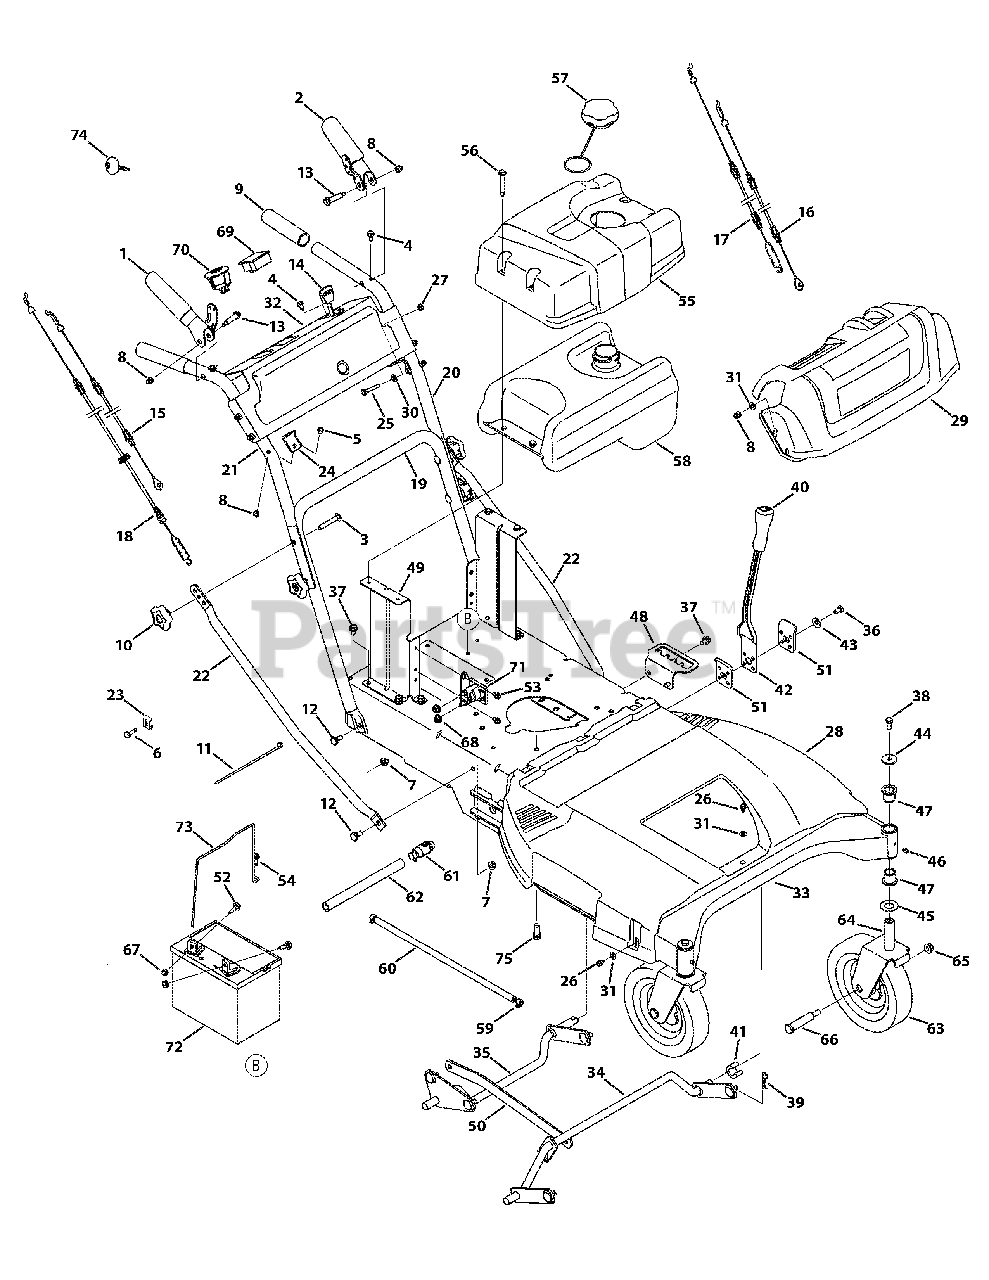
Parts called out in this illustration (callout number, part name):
1	Right Hand Lever Assembly Bracket
2	Left Hand Lever Assembly Bracket
3	Screw, Carriage, 5/16-18 x 2.25
4	Screw, 1/4-20 x 0.500
5	Hex Screw, 1/4-20 x 1.50
6	Screw, #10-32 x 0.625
7	Nut, Flangelock, 5/16-18
8	Lock Nut Cap, 1/4-20
9	Grip, 1.0 ID x 5.0 LG
10	Star Knob, 5/16-18
11	Cable Tie, 3/16 x .05 x 7.4
12	Screw, Shoulder, .435 x .178-5/16 x .56
13	Screw, Shoulder, .375 x 1.355 x 1/4-20
14	Throttle/Choke Cable, 38.0 x 1.1 EXT
15	RH Brake Cable
16	LH Brake Cable
17	Wheel Clutch Cable
18	Deck Clutch Cable
20	Upper LH Handle
21	Upper RH Handle
22	Adjustable Handle Brace
23	Casing Clamp
24	RH Cable Mount Bracket
24	LH Cable Mount Bracket
25	Hex Screw, 1/4-20 x 1.75
26	Screw, 1/4-14 x 0.625
27	Nut, Hex, 1/4-20
28	Belt Cover
29	Handle Panel, Black
30	Washer, Bell, .265 x .75 x .062
31	Washer, Flat, .25 x .630 x .0515
32	Hour Meter and Key Handle Panel
33	Frame Assembly
34	Front Deck Lift Assembly
35	Rear Deck Lift Assembly
36	Hex Screw, 5/16-18 x .50
37	Screw, 5/16-18 x 0.625
38	Hex Screw, 5/16-24 x .750
39	Click Pin, .092 x 1.64 LG
40	Grip Handle, 1/2
41	Plastic Spacer, .63 ID x .75 LG
42	Deck Height Lever
43	Washer, Bell, .340 x .872 x .060
44	Washer, Flat, .330 x 1.25 x .120
45	Washer, Flat, .760 ID x 1.50 OD
46	Drive Lube Fitting, 3/16
47	Flange Bearing, .760 x .941 x 1.0
48	Height Adjustment Bracket
49	Fuel Tank Mount Bracket
50	Link Pivot Bracket
51	Lever Pivot Bracket
52	Hex Head Flange, 1/4-20 x .75
53	Screw, 1/4-20 x 0.500
54	Screw, 1/4-20 x 0.750
55	Fuel Tank Cover
56	Screw, Shoulder, 1/4-20 x .32 x 1.8
59	Hose Clamp, .490 DIA.
60	Fuel Hose, Low Permeation, 1/4
62	Extension Hose
63	Caster, Wheel, 8 x 1.75
64	Wheel Caster Bracket
65	Nut, Flangelock, 3/8-16
66	Bolt, Shoulder, .625 x 2.515 x 3/8-16
67	Sems Nut, 1/4-20
68	Nut, Flangelock, 1/4-20
70	Key Switch
71	Solenoid, 12V, 100 AMP
72	Battery, 155 CCA WET
73	Battery Hold Down Strap
74	Key, Yellow
74	Key w/ plastic cover
75	Screw, 3/8-16 x 1.250
